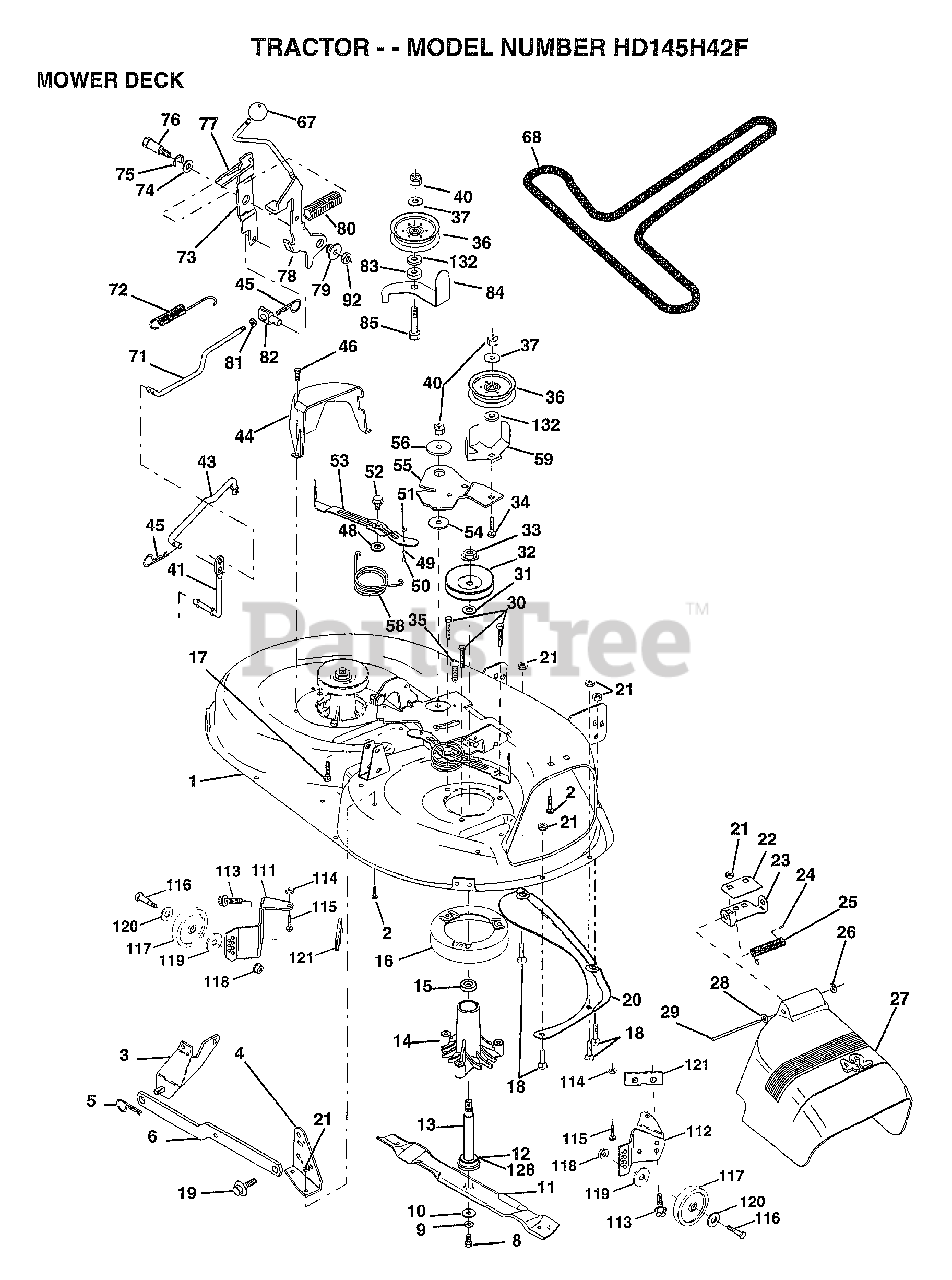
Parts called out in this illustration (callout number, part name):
1	DECK.WELD.42.
2	BOLT
3	BRKT ASM SWAY BAR
4	BRKT DECK SW BAR
8	BLADE BOLT
10	WASHER.HARD.BLADE
11	"BLADE.42"" HIPERF"
12	BEARING.BALL
14	HSG ASM MANDREL
15	BEARING
16	STRIPPER RND MWR
17	BOLT RDHD 3/8-16
18	BOLT
19	BOLT SHD 5/16-18
22	STIFFENER BRKT
23	DEFLECTOR BRKT
24	CAP-SLEEVE LT
25	SPRING TORSION
26	NUT PUSH M
27	DEFLECTOR.SHIELD
28	WASHER
29	HINGE ROD
30	SCREW THDROL WASHER HEAD
31	WASHER
32	PULLEY.MANDREL.42
34	BOLT
35	XMAS TREE FASTNER
36	FLAT IDLER PULLEY
37	WASHER
41	PIVOT ROD
43	ROD CLUTCH W/NIBS
44	GUARD MAND LH BLK
45	RETAINER M
46	SCREW.1/4-20X5/8
48	HARD SMALL WASHER
49	ROLLER ASM-CAM
50	SHOULDER BOLT
51	LOCKNUT
52	BOLT.SHLD.5/16-18
54	HARDENED WASHER
55	ARM-IDLER
56	SPACER RETAINER
58	SPRING TORSN BRAK
59	GUARD IDLER TUV
67	KNOB T(3/8 HOLE)
68	BELT.V.T-PATH
71	ROD CLUTCH 38/42
72	RETURN SPRING
73	CLUTCH ARM SECOND
74	WASHER
75	RING
76	SHOULDER BOLT
77	SPRING KEEPER
78	LEVER ASM-CLUTCH
79	BUSHING
80	SPRING.CLUTCH.MWR
81	NUT
82	TRUNION ADJ
83	WASHER
84	"KEEPER-BELT,FIXED"
85	BOLT RDHD 3/8-16
92	NUT
111	BRACKET.GWHL.LH.
112	BRACKET.GWHL.RH.
113	SCREW
116	BOLT M
117	WHEEL.GAGE.BLK.PL
118	LOCKNUT
119	WASHER
120	WASHER
121	BRACKET.EXTRD.GWL
128	WASHER.FELT.
132	WASHER GT
